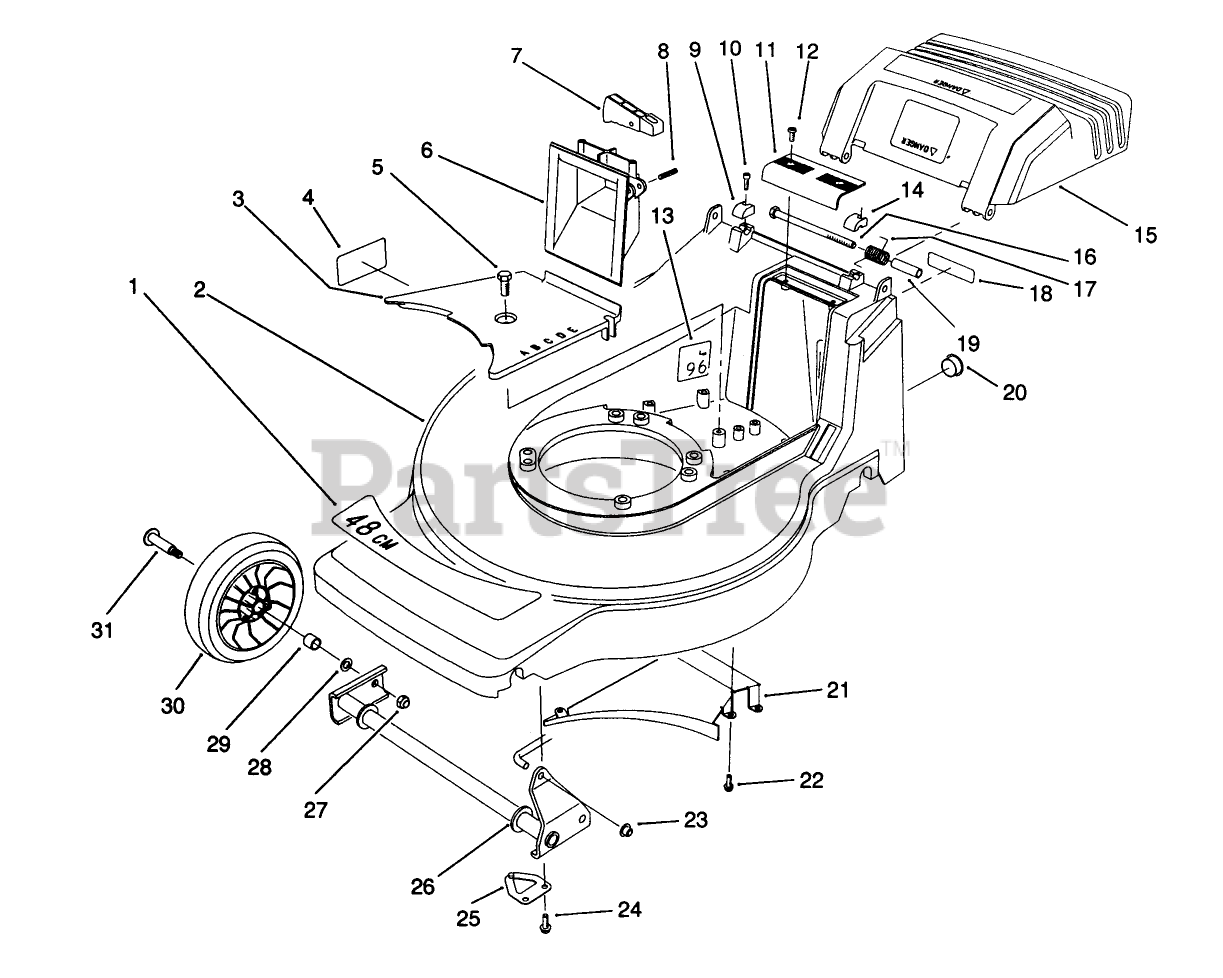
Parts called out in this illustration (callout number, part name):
5	SCREW-HWHTF
6	GRIP - LOWER
7	TRIGGER - HOC
9	CAP-HINGE BOLT, RH
10	SCREW-HSH
11	GRIP-UPPER
12	SCREW-PPH, PLASTITE
14	CAP-HINGE BOLT, LH
15	HP DISCHARGE DOOR
16	SCREW-HH
19	SPACER-DOOR
22	SCREW-HWHTF
23	NUT-PUSH
26	FRONT PIVOT WA
27	NUT-HEX
28	WASHER
29	BUSHING
31	BOLT-WHEEL
